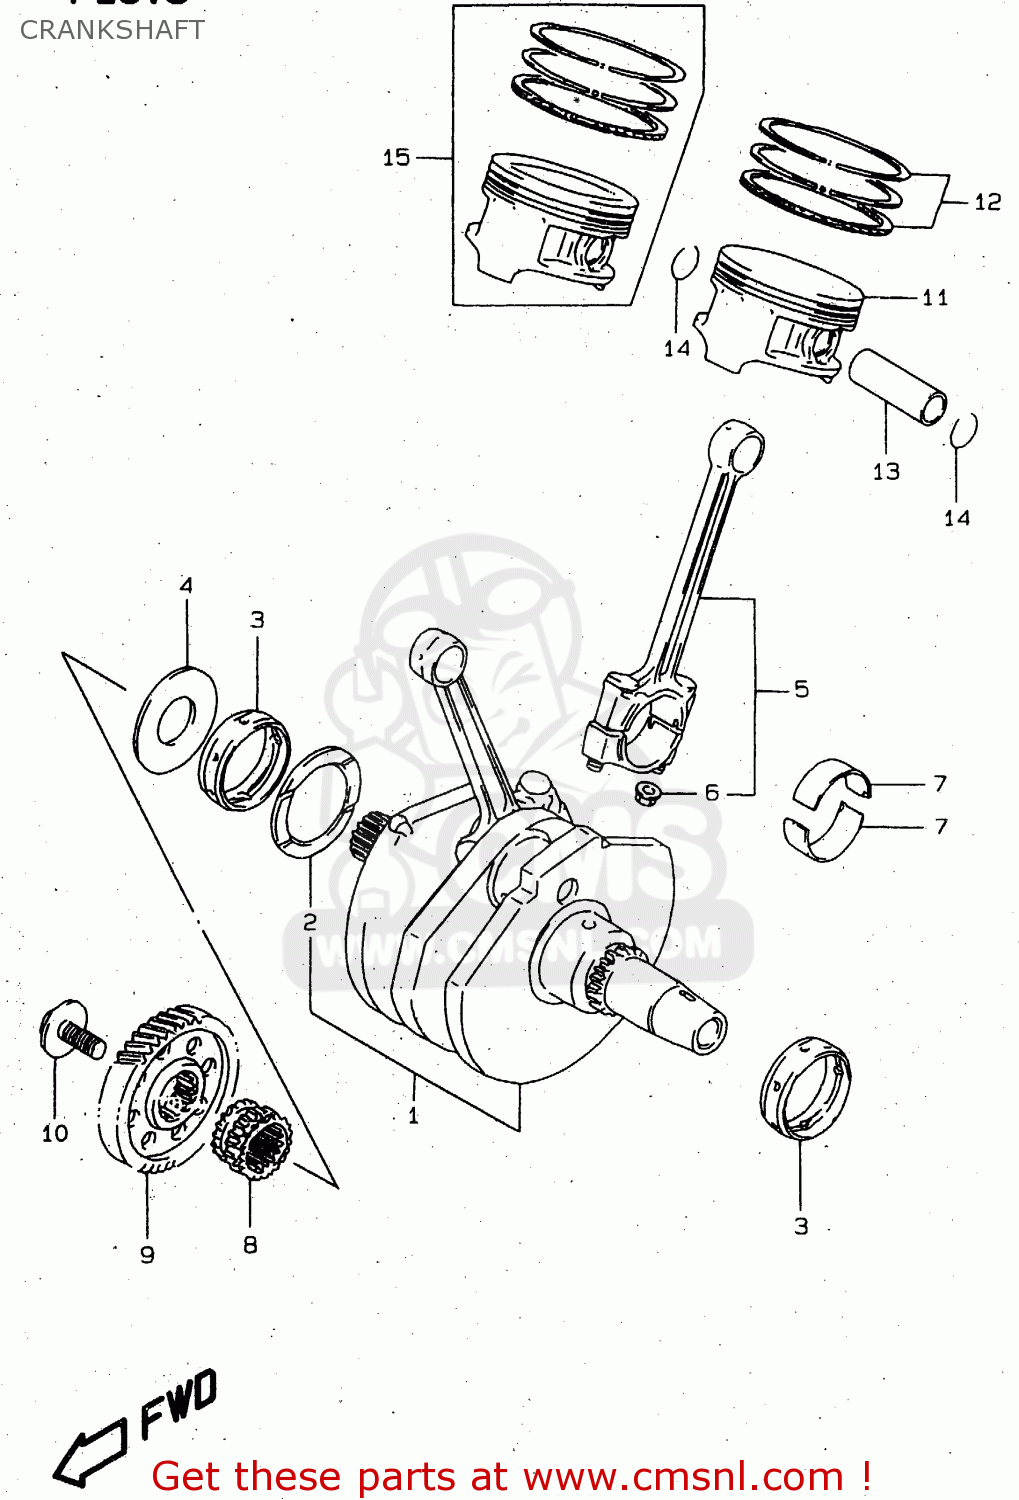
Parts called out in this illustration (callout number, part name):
1	CRANKSHAFT SET
2	WASHER(48.1X64X1.94)
3	METAL,CRANKSHAFT
4	WASHER,CRANK THRUST
5	CONNECTING ROD ASSY
6	NUT
7	BEARING,CRANK PIN
8	SPROCKET,CAM CHAIN DRIVE,R
9	GEAR,PRIMARY DRIVE
10	BOLT(12X28)
11	PISTON
12	RING SET,PISTON
13	PIN,PISTON
14	CIRCLIP,PISTON PIN
15	PISTON SET(OS:0.5)
